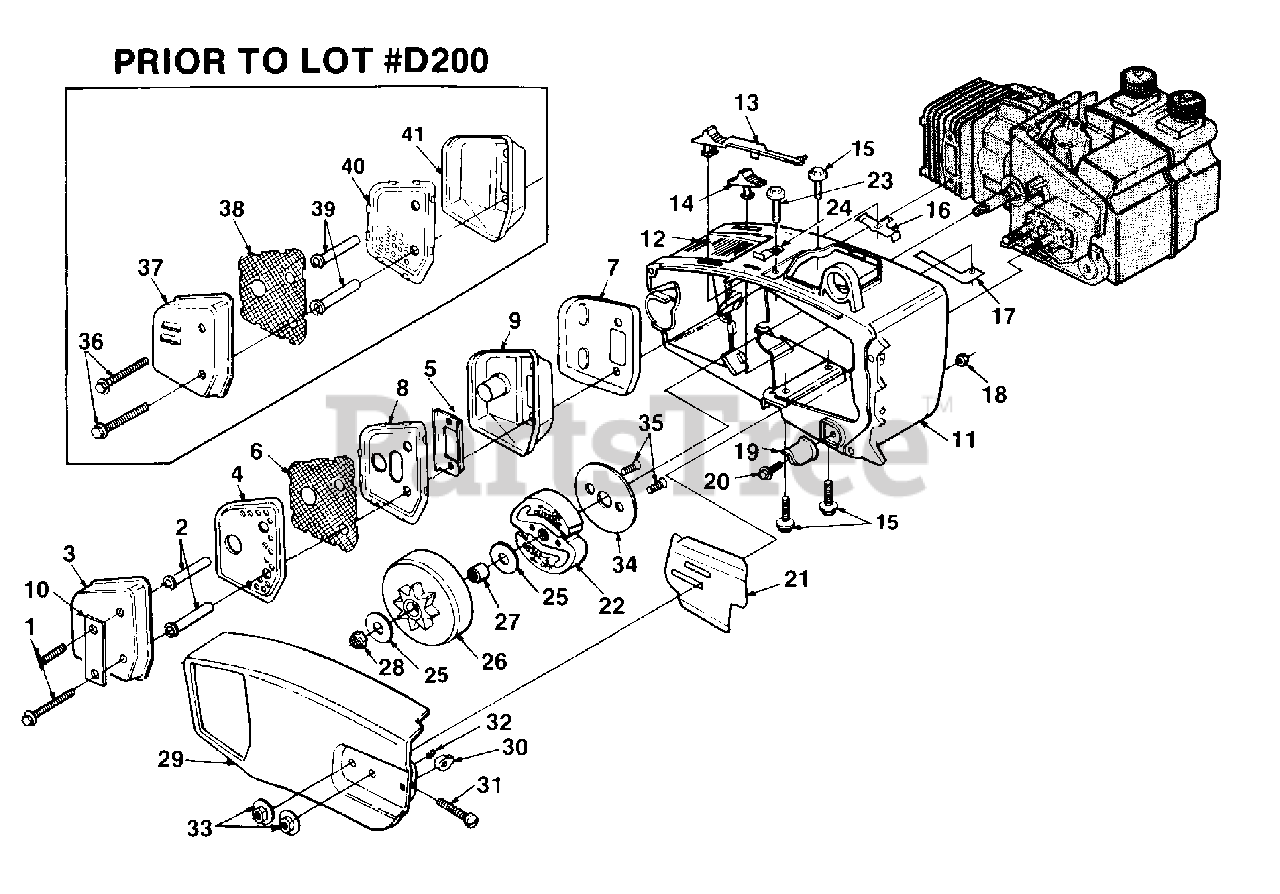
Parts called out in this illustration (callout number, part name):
2	SPACER- Muffler
3	CAP- Muffler
4	BAFFLE- Muffler
5	PLATE- Muffler
6	SCREEN- Spark arrestor
7	DEFLECTOR- Exhaust
8	BAFFLE- Muffler
9	BODY- Muffler
10	BRACKET- Muffler
11	HOUSING- Engine
12	DECAL- Warning
13	BUTTON- Choke
14	BUTTON- Stop switch
15	SCREW- Hex sems 10-24 x 5/8
16	SPRING- Stop switch
17	CONTACT- Stop switch
18	NUT- Lock 10-24
19	STOP- Chain
20	SCREW- Mach hex 10-24 x 5/8
21	PLATE- Guide bar
22	CLUTCH- S
23	SCREW- Sems hex (10-24 x 3/4)
24	BRACE- Choke
25	WASHER- Thrust
26	SPROCKET & DRUM (37/375 chain only) 6T
27	BEARING- Needle
28	NUT- Lock 5/16-24
29	COVER- Drivecase
30	PIN- Guide bar adjusting
31	SCREW- Guide bar adjusting
32	"E" RING
33	NUT- Flange 1/4-20
34	COVER- Clutch
35	SCREW- Flat hd. 10-32 x 1/2
36	SCREW- Hex sems 10-24 x 2 (prior to Lot #D200)
37	CAP- Muffler (prior to Lot PD200)
38	SCREEN- Spark arrestor (prior to Lot #D200)
39	SPACER- Muffler (prior to Lot #D200)
40	BAFFLE- Muffler (prior to Lot #D200)
41	BODY- Muffler (prior to Lot PD200)
